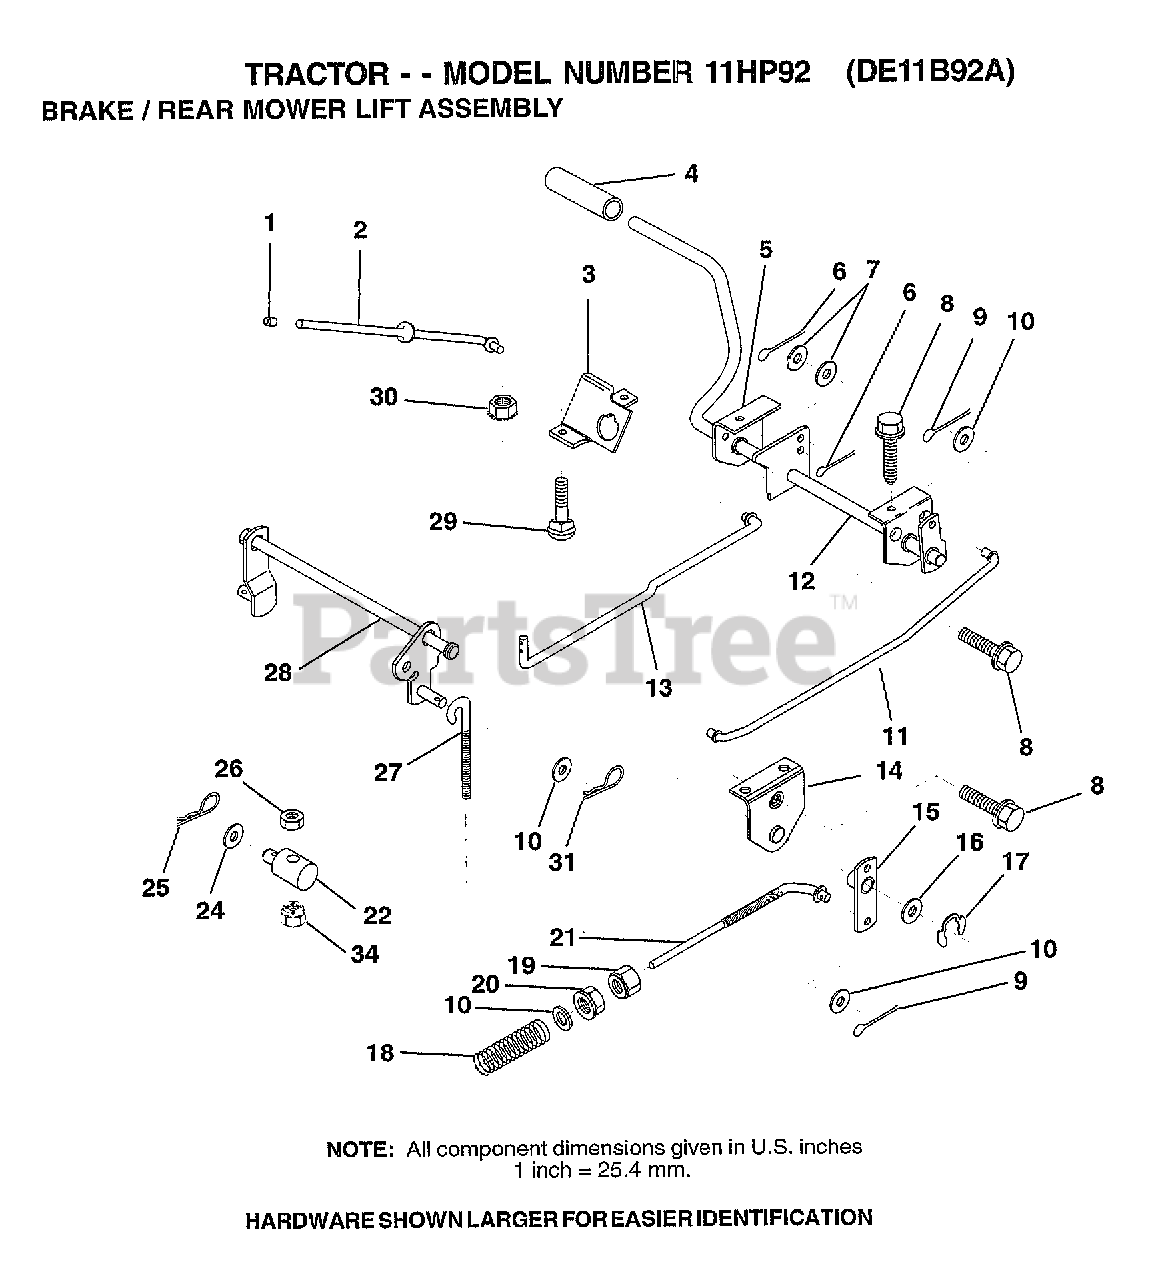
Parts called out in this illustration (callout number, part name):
1	PLUNGER CAP T
2	"ROD,PARK BRAKE"
3	"BRKT,PARK BRAKE"
4	FOOT PEDAL COVER
5	"BRKT,CLU PEDAL LH"
7	WASHER
8	SCREW LT
9	COTTER PIN
10	WASHER
11	"ROD,FRT BRAKE"
12	PEDAL ASM CL/BK36
13	"ROD,CLUTCH"
14	"BRKT,LIFT SHAFT"
15	PVT BRAKE ARM ASM
16	WASHER T
17	KLIP RING
18	SPRING ROD BRAKE
19	NUT
20	NUT
22	TRUNNION.LIFT.
24	WASHER
25	SPRING.RETAINER
26	LOCKNUT
27	"LINK, MOWER REAR"
28	LIFT ASM MOW REAR
31	RETAINER.SPRING
